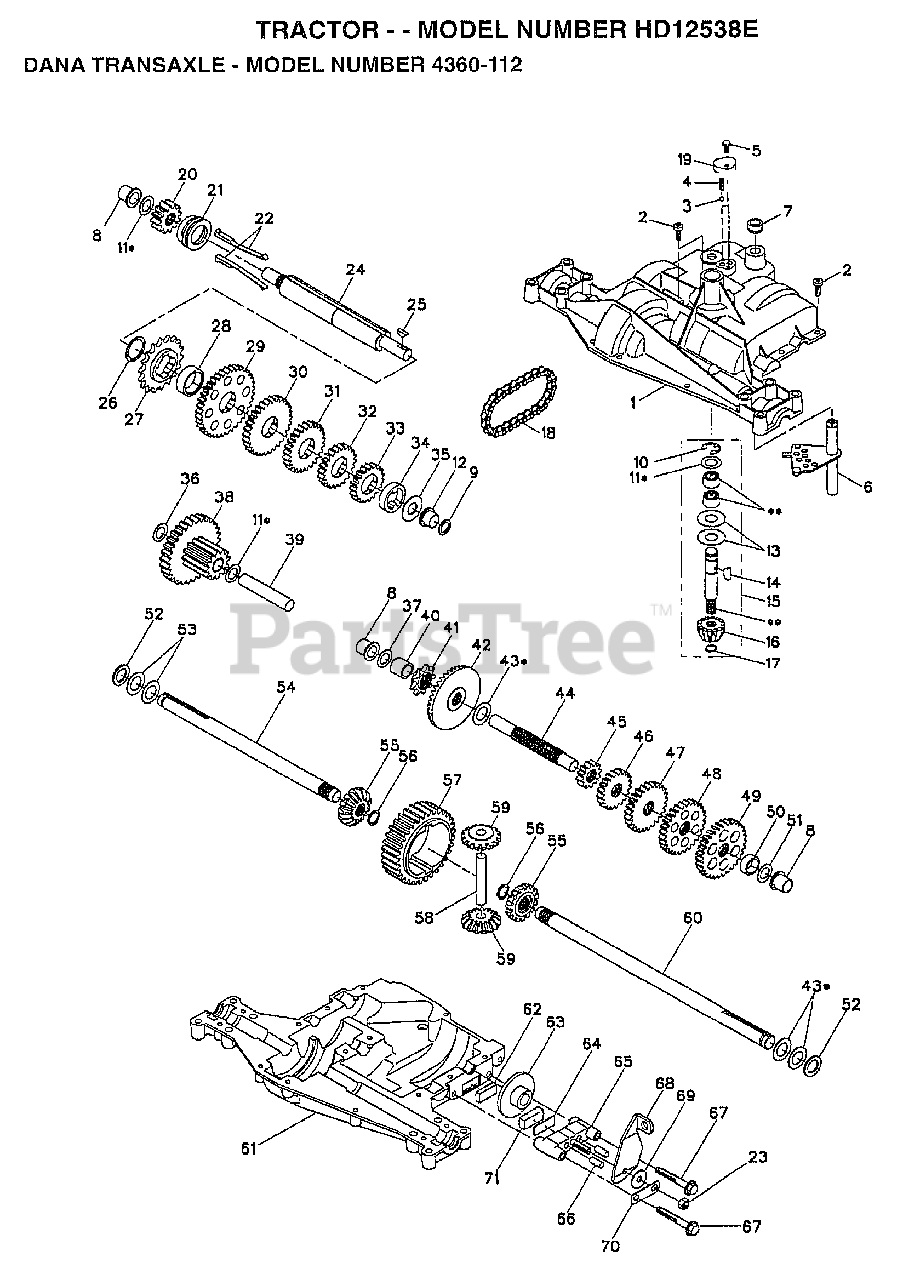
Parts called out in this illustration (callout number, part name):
1	HOUSING, UPPER
3	BALL, DETENT
4	SPRING, DETENT
5	SCREW, #10-24 X .482
6	SHIFTER ASSEMBLY
8	BEARING, FLANGE
10	RING, RETAINING
11	ASSY, KIT, SHIM .625 SHAFT
12	BEARING, FLANGE
13	WASHER, PLAIN .632 X 1.38 X .046
14	KEY, WOODRUFF, #9
15	ASSEMBLY, KIT, INPUT SHAFT
16	PINION, BEVEL, 14 TEETH
17	RING, RETAINING
18	CHAIN, 24 PITCHES
19	COVER, DETENT
20	GEAR, SPUR, 12T
21	COLLAR, CLUTCH
22	ASSEMBLY, KIT, CLUTCH KEYS
23	LOCKNUT 5/16-24
24	SHAFT, INTERMEDIATE
25	KEY, WOODRUFF, #61
26	RING, RETAINING
27	SPROCKET, 18 TEETH
29	GEAR, SPUR, 37 TEETH
30	GEAR, SPUR, 30 TEETH
31	GEAR, SPUR, 25 TEETH
32	GEAR, SPUR, 22 TEETH
33	GEAR, SPUR, 19 TEETH
35	WASHER, PLAIN .640 X 1.37 X .061
36	WASHER PLAIN
37	WASHER PLAIN
38	ASSY, GEAR COMB 12T & 30T
39	SHAFT, IDLER
40	SPACER .635 X .875 X .755
41	SPROCKET, 9 TEETH
42	GEAR, BEVEL, 42 TEETH
43	ASSY, KIT, SHIM .750 SHAFT
44	SHAFT, DRIVE
45	GEAR SPUR, 12 TEETH
46	GEAR, SPUR, 20 TEETH
47	GEAR, SPUR, 25 TEETH
48	GEAR, SPUR, 28 TEETH
49	GEAR, SPUR, 31 TEETH
51	WASHER, PLAIN .632 X 1.00 X .060
52	WASHER, NEOPRENE
53	WASHER, PLAIN .758 X 1.25 X .031
55	GEAR, MITER, 15 TEETH
56	RING, RETAINING
57	GEAR, SPUR, 32 TEETH
58	SHAFT, CROSS
59	GEAR, MITER, 15 TEETH
61	HOUSING, LOWER
62	PUCK, FRICTION
63	DISC, BRAKE
65	JAW, BRAKE
66	PIN, DOWEL
67	SCREW, 5/16-18 X 2.35
68	LEVER ACTUATING
69	WASHER, PLAIN .321 X 1.00 X .055
70	BRACKET, ANTI-ROTATION
71	PUCK, FRICTION
